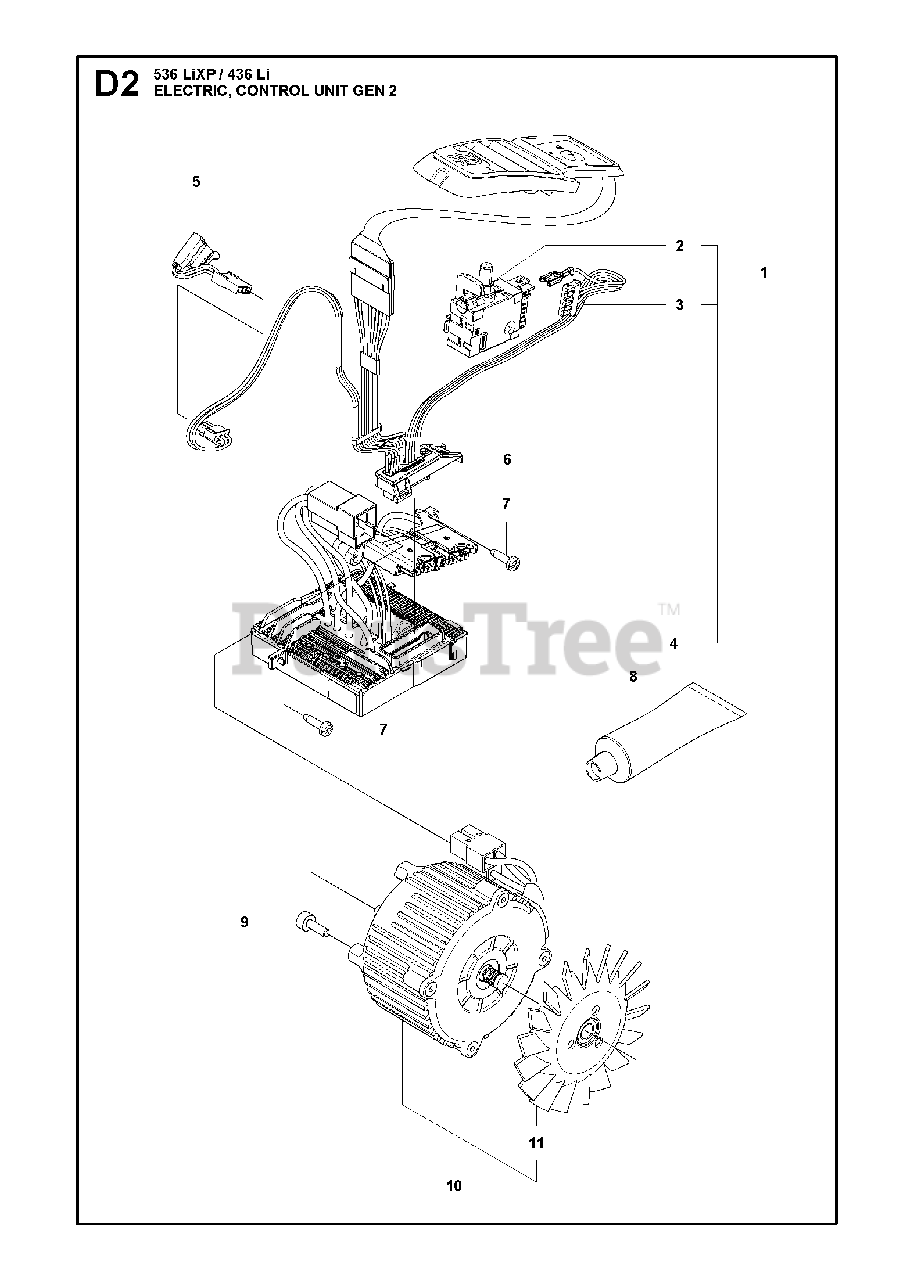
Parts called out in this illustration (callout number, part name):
1	CONTROL UNIT
2	TRIGGER SWITCH
3	WIRING ASSY SIGNAL REAR HANDLE
4	CONTROL UNIT
5	WIRING ASSY
8	GREASE TUBE Q8 RUYSDAEL WR2
10	MOTOR ASSY BLDC D70
